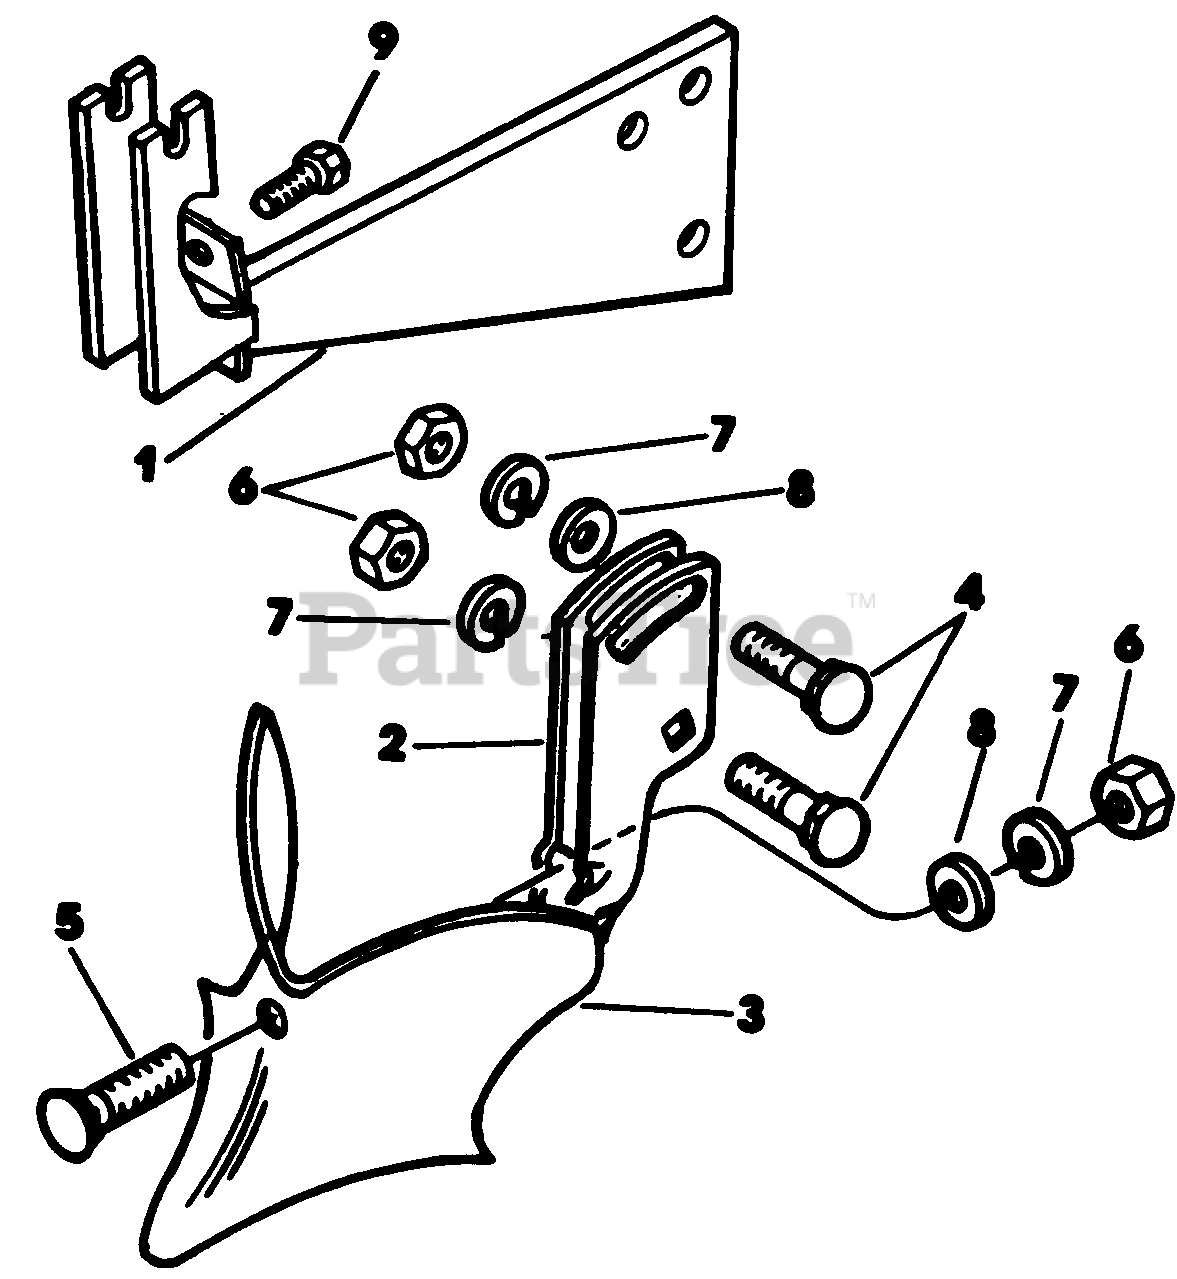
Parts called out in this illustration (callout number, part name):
1	Support
2	Holder
3	Shovel
4	Carriage Bolt 3/8-16 x 1-1/4 Plated
5	Plow Bolt 3/8-16 x 2" Plated
6	Nut, Hex 3/8-16 Plated
7	Washer, Spring Lock 3/8 Plated
8	Washer, Flat 3/8 Plated
9	Cap Screw, Hex Hd. 5/16-18 x 5/8 Plated Grade 5
